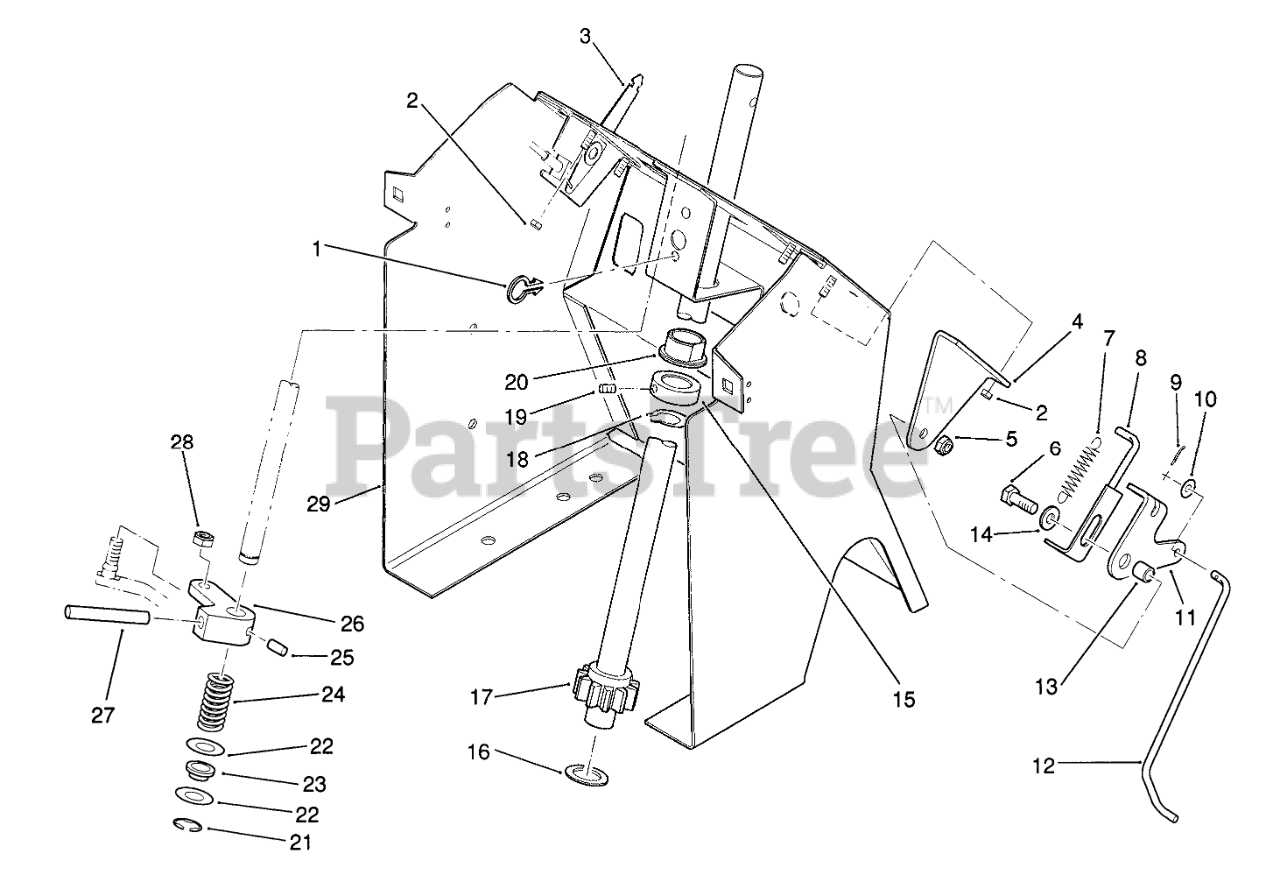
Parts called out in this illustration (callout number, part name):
1	CLIP-SNAP IN
2	Nut
3	Control-Throttle
4	SUPPORT-INDICATOR B
5	Nut
6	Bolt
7	SPRING-EXTENSION
8	WLDMT-INDICATOR R
9	Cotter Pin
10	Washer
11	RETAINER-INDICATO B
12	ROD-INDICATOR
13	SPACER
15	BEARING-FLANGED
16	WASHER
17	WLDMT-STRG SHAFT
18	RING-RETAINING
19	SCREW-SET
20	COLLAR
21	Snap Ring
22	SHIM-WASHER
23	BUSHING-NYLINER
24	SPRING-COMPRESSION
25	PIN-SPIROL
26	ARM-SPEED CONTROL
27	PIN-SPIROL 5/16X2.25
28	5/16-24 E.S. NUT
29	WLDMT-HOODSTAND B
